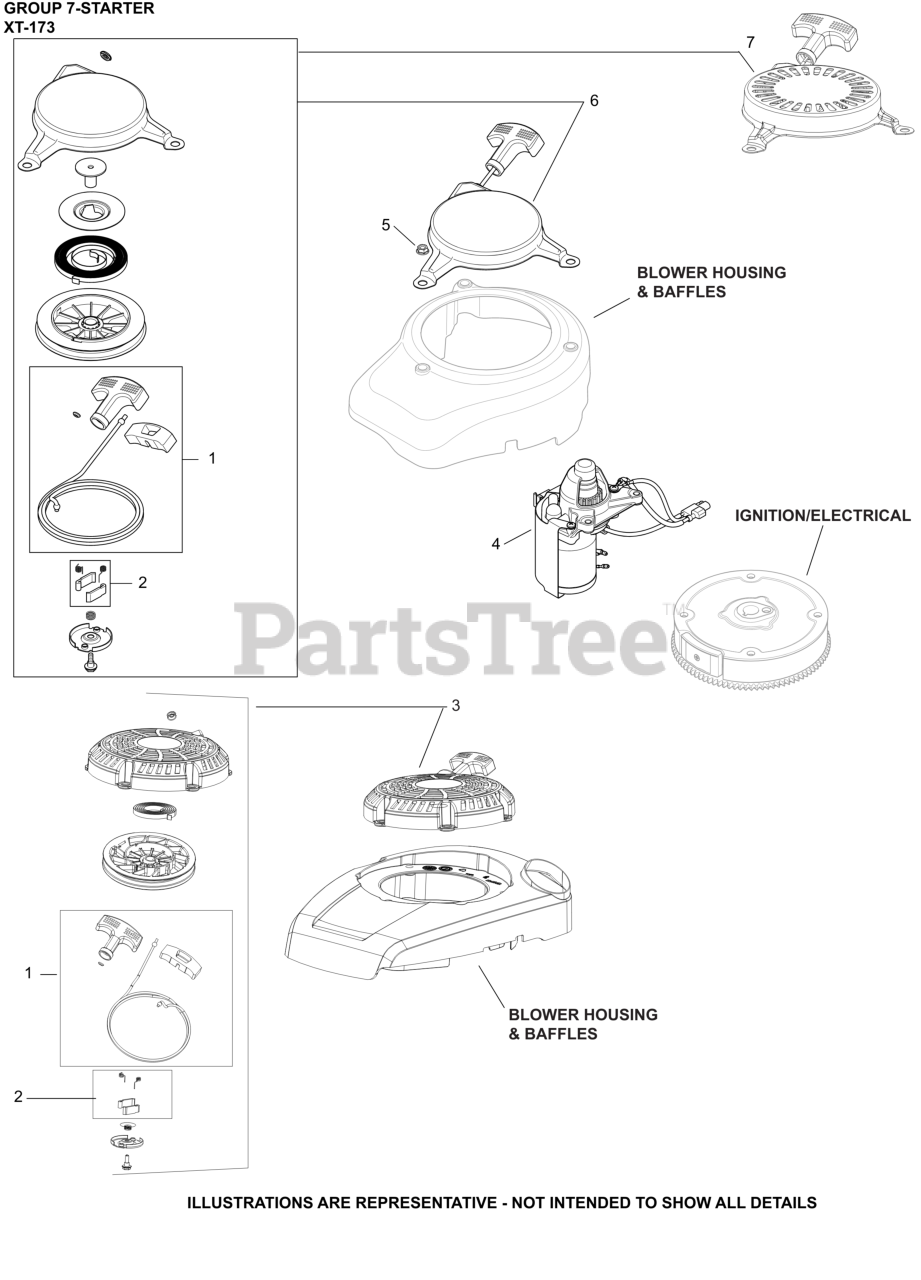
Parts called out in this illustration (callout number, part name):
1	KIT, STARTER ROPE W/HANDLE
4	ELECTRIC STARTER-USE 14 098 05-S
6	STARTER ASSY, (W/HANDLE)-USE 14 165 07-S
NI	ELECTRIC STARTER-BENDIX DRIVE
NI	SCREW, SHOULDER (M5)
